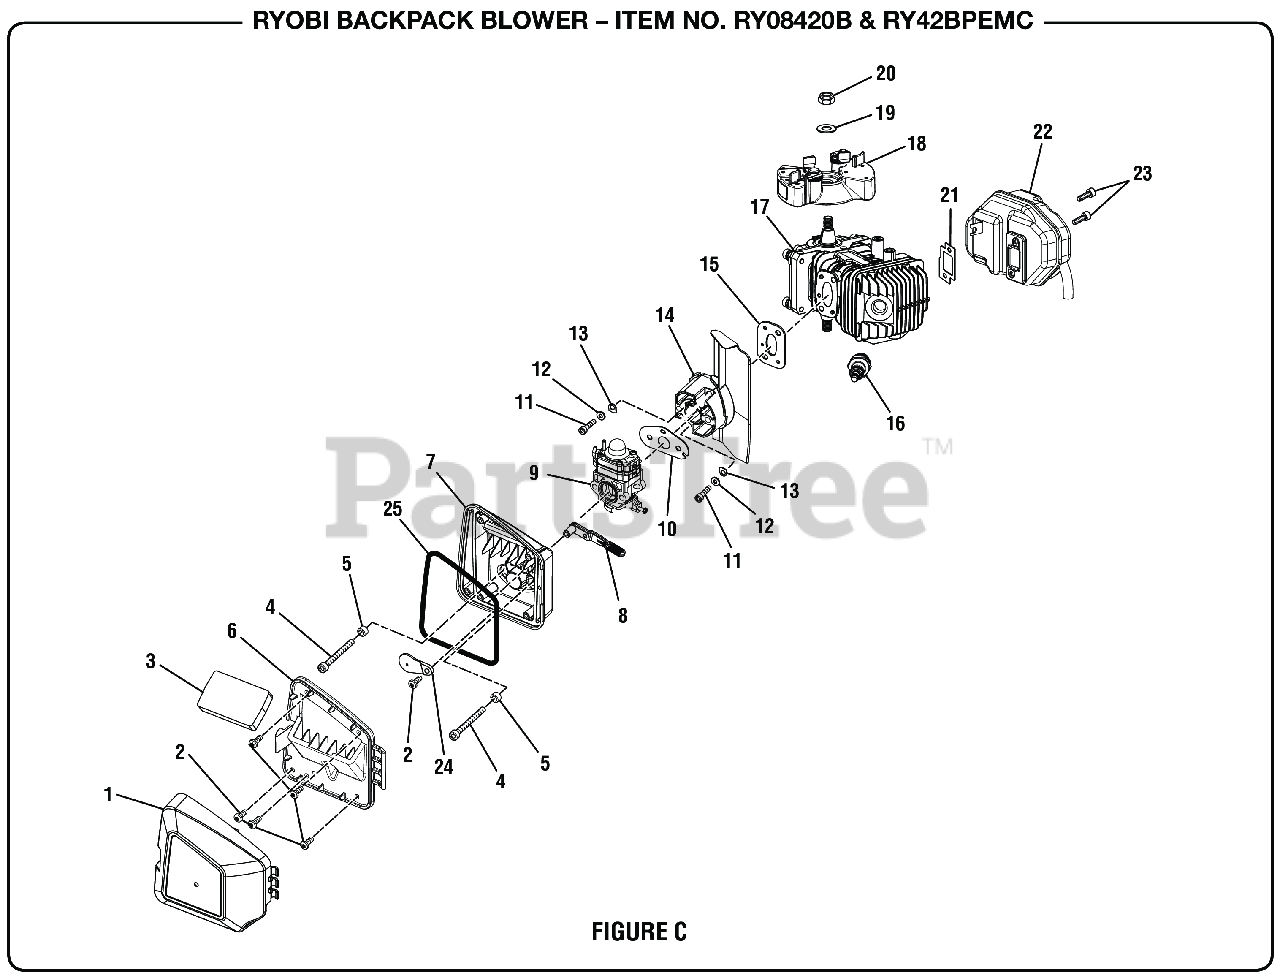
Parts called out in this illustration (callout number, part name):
1	Air Box Cover
2	Screw (M4 x 12 mm, Slotted Recessed Pan Hd.)
3	Air Filter
4	Cap Screw (M5 x 45 mm, T25 Torx Soc. Hd.)
5	Washer (ID5.8 x OD11.5 x 1.7t)
7	Air Box Base
8	Choke Lever
9	Carburetor (Walbro, WYJ-536)
10	Gasket Carb-Heat Dam
11	Screw (M5 x 0.8 in.)
12	Spring Washer (M5)
13	Washer (Heat Dam)
15	Heat Dam Gasket
16	SPARK PLUG (CHAMPION RCJ4)
17	Short Block Assembly
18	Flywheel Assembly
19	Washer (ID9 x OD17.7 x 1.1t)
20	Lock Nut (M8)
22	Exhaust Assembly
23	Screw (1/4-20 x 5/8 in.)
24	Choke Plate
25	Airbox Gasket
